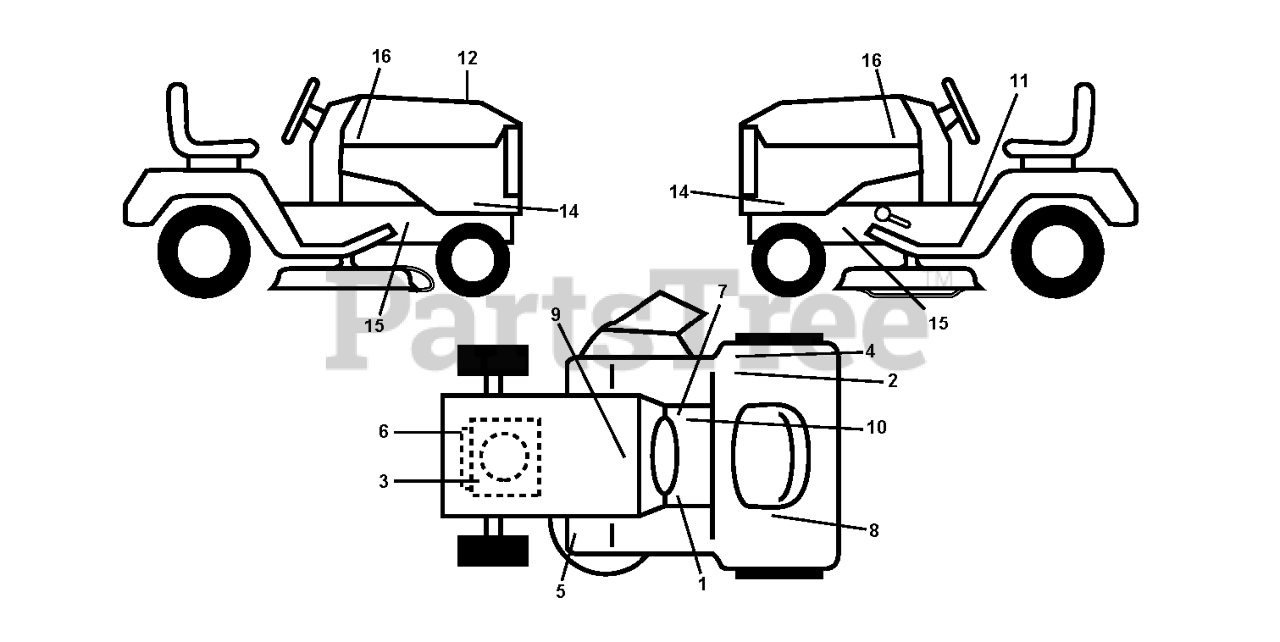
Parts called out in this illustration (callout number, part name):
1	DECAL
2	DECAL
3	DECAL.ENG.BS26HP.ENDUR.27947
4	DECAL 80 DBA
5	DECAL.PEDAL.HUSQ.CROWN
6	DECAL
7	DECAL PARK BRAKE
8	DECAL.WARN.RESERVE.FUEL
9	DECAL BTRY SYMBOLS
10	DECAL
11	LABEL
16	RP.DECAL.BADGE.170MM.TEXTLOGO
